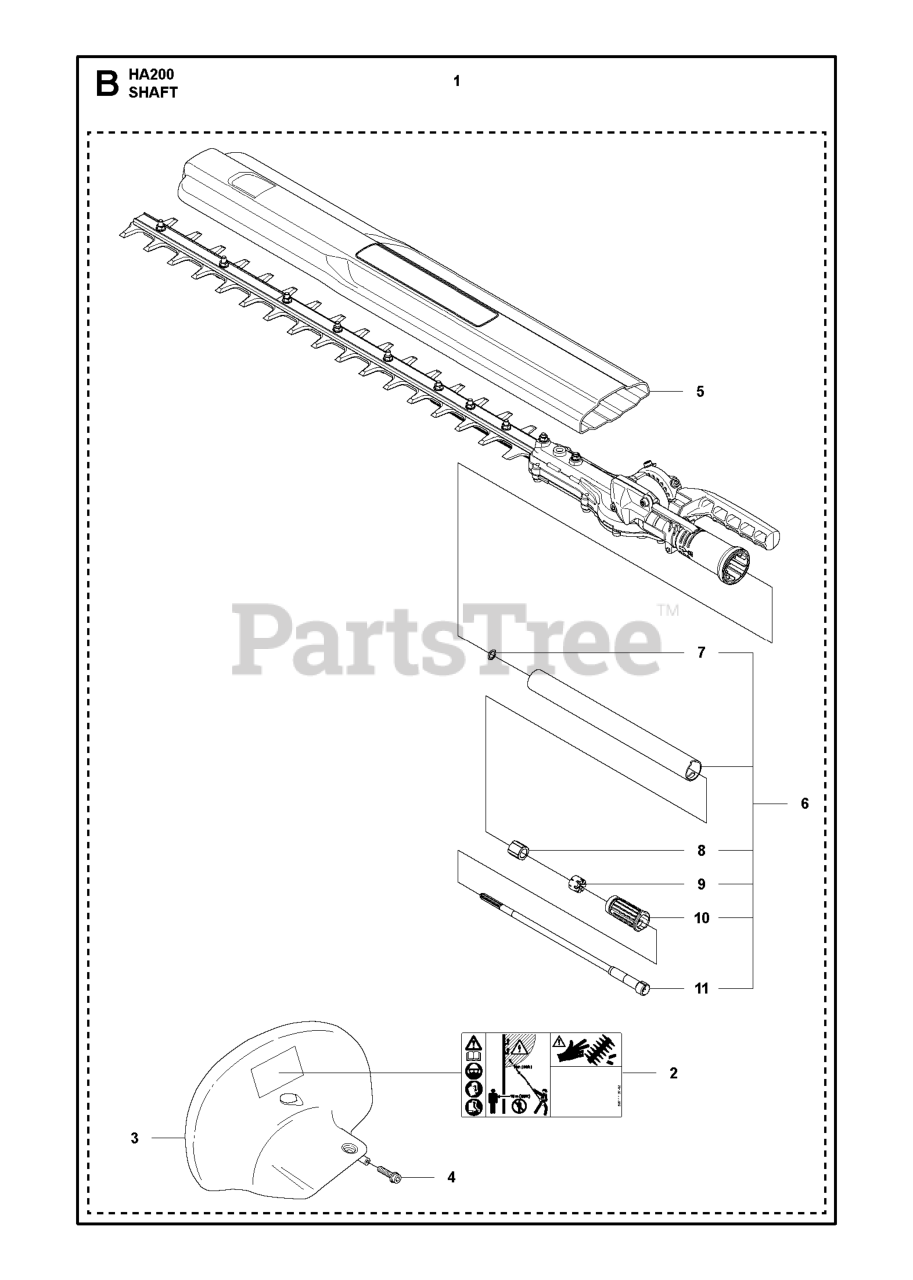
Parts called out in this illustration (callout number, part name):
2	LABEL WARNING
3	Handguards
4	SCREW
5	TRANSPORT GUARD HUSQVARNA GRE
11	Drive Shafts
